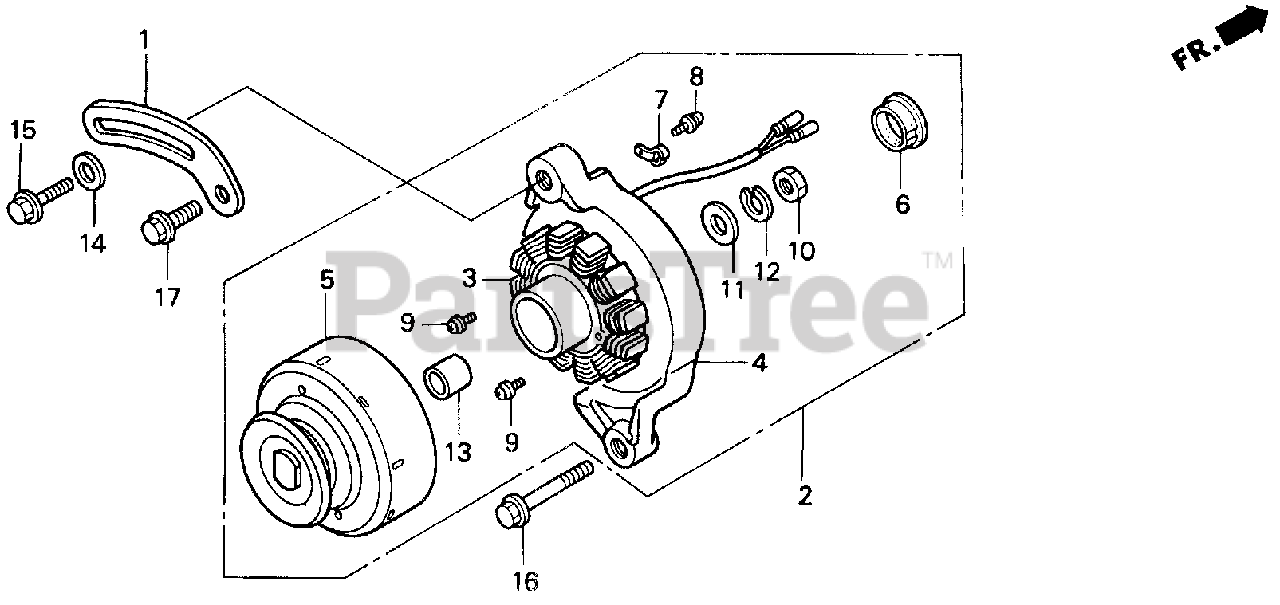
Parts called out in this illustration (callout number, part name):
1	STAY, ALTERNATOR
2	ALTERNATOR ASSY. (15A)
6	CAP, RUBBER
7	CLIP, WIRE
8	SCREW-WASHER (4X8)
9	SCREW-WASHER (4X24)
10	NUT, HEX. (10MM)
11	WASHER, PLAIN (10MM)
12	WASHER, SPRING (10MM)
13	COLLAR, SPACER
14	WASHER, PLAIN (8MM)
15	BOLT, FLANGE (8X25)
16	BOLT, FLANGE (8X45)
17	BOLT, FLANGE (10X22)
